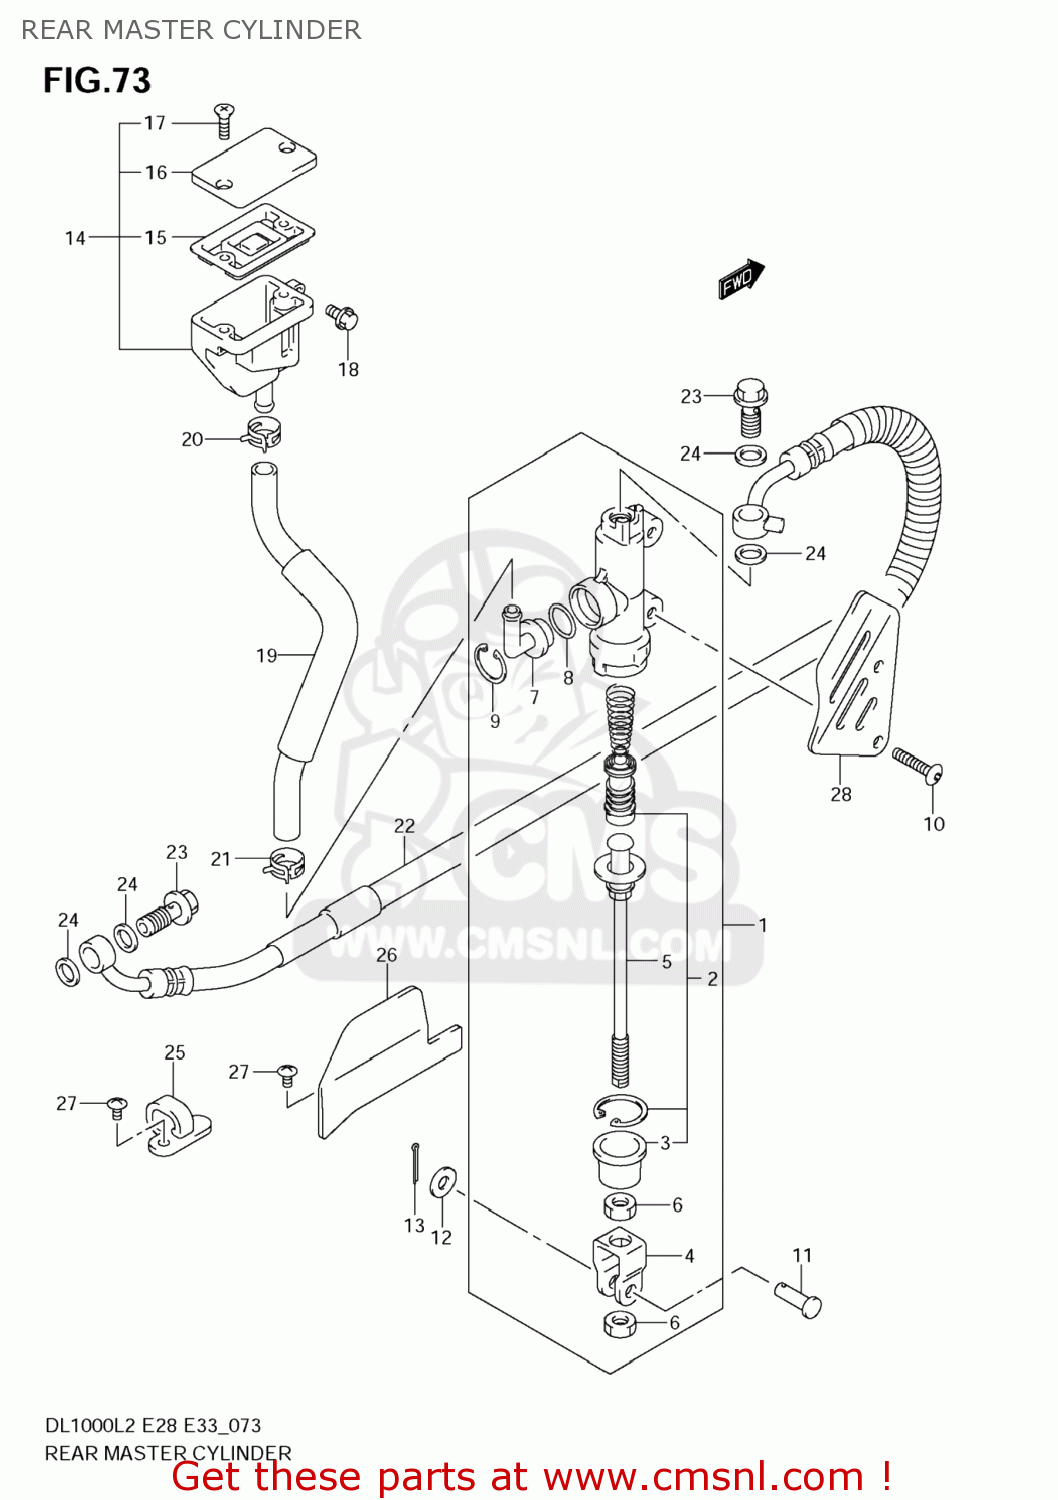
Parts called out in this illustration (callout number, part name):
1	CYLINDER ASSY,RR MASTER
2	PISTON/CUP SET
3	BOOT
4	YOKE
5	ROD,PUSH
6	NUT
7	CONNECTOR
8	O RING
9	CIRCLIP
10	SCREW(6X25)
11	PIN(6X18.2)
12	WASHER
13	PIN
14	TANK ASSY,RR RESERVOIR
15	DIAPHRAGM
16	CAP
17	SCREW
18	BOLT
19	HOSE,RR RESERVOIR TANK
20	CLIP
21	CLIP
22	HOSE,RR BRAKE
23	BOLT UNION
24	WASHER(10X15X1.5)
25	GUIDE,RR BRAKE
26	GUIDE,RR BRAKE HOSE FR
27	SCREW
28	COVER,RR MASTER CYLINDER
